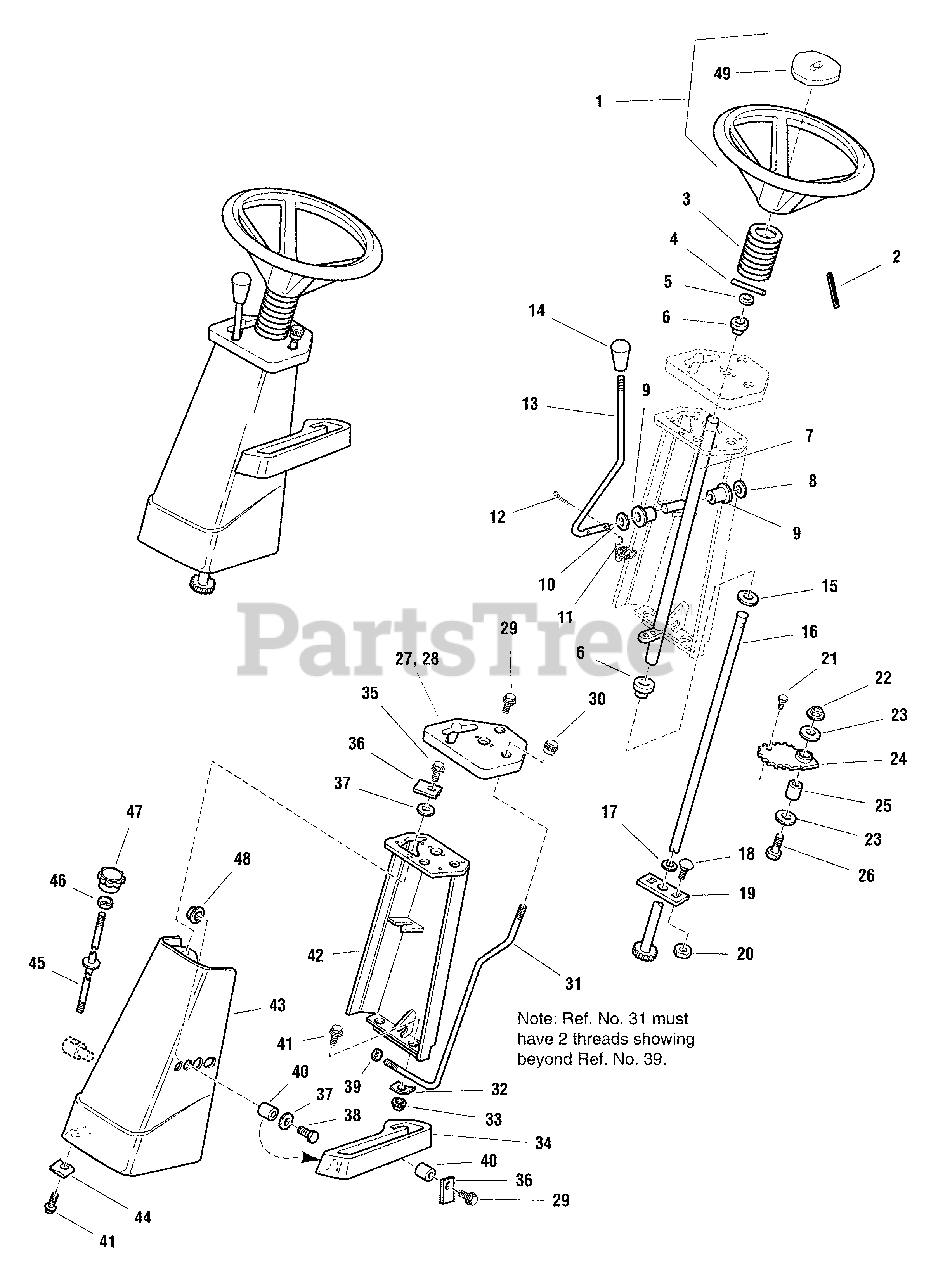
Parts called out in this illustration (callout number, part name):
1	STEERING WHEEL ASSEMBLY (Includes Ref. No. 49)
3	TUBE, Steering
5	WASHER, 49/64
7	TUBE ASSEMBLY, Shift
8	WASHER
10	WASHER, Plain, 17/32 x 1-1/4 x 7/64
11	SPRING, Torsion
12	COTTER PIN
13	ROD, Shift
14	KNOB, Rod, Shift
15	WASHER, Plain, 11/32 x 1 x 1/8
16	SHAFT ASSEMBLY, Steering
17	WASHER, Plain
18	CARRIAGE BOLT, 3/8-16 x 1
19	PLATE, Steering Mounting
20	NUT, Hex, 3/8-16
21	CAPSCREW, Hex Head, 5/16-18 x 1-1/2
22	NUT, Hex, Flange Lock, 3/8-16
23	WASHER, 13/32 x 1-1/2 x 1/8
24	GEAR, Steering
26	CAPSCREW, Hex Head, 3/8-16 x 2
27	DASH, Hydro
28	DASH, Gear
29	CAPSCREW, Hex, Flange, Taptite, 1/4-20 x 3/4
30	KNOB, Rod, Parking Brake
31	ROD, Parking Brake
32	PUSH NUT, 5/16
33	NUT, Hex, Flange, Whizlock, 5/16-18
34	QUADRANT, Lift
35	CAPSCREW, Hex Head, Taptite, 1/4-20 x 1/2
37	WASHER, Plain, 1/4
38	CAPSCREW, Hex Head, 1/4-20 x 7/8
39	NUT, Hex, Flange Centerlock, 1/4-20
40	SPACER, 17/64 x 3/8 x 21/64
41	CAPSCREW, Hex Head, Whizlock, 5/16-18 x 3/4
42	SUPPORT, Steering
43	SHROUD, Front (Orange)
43	SHROUD, Front (Red)
44	NUT, Speed, Lug Type, 5/16-18
45	ROD, Lift Height
46	NUT, Hex, Jam, 1/4-20
47	KNOB, Rod, Lift Height
48	NUT, Hex, Flange, Whizlock, 1/4-20
